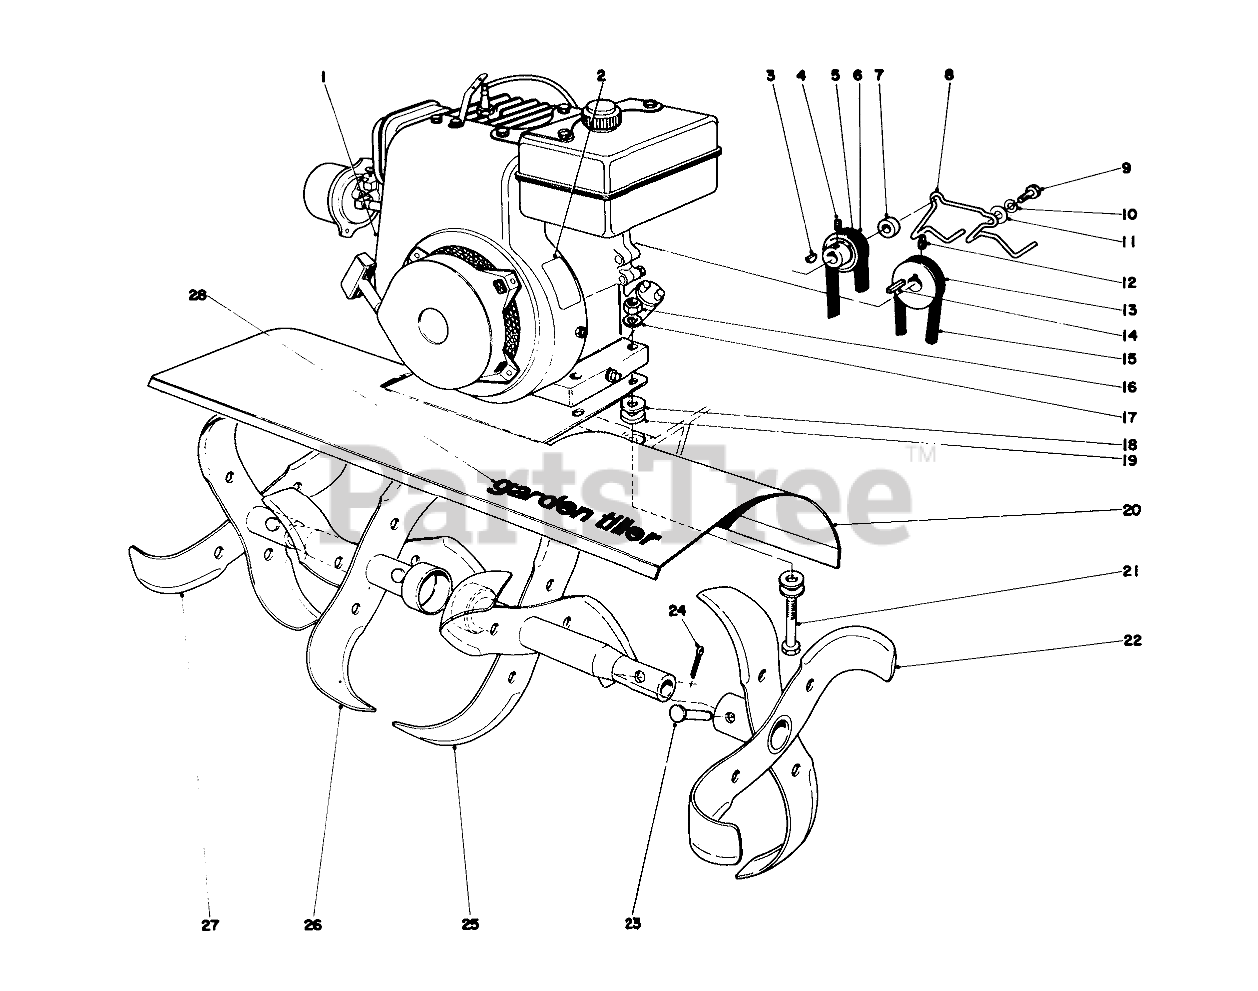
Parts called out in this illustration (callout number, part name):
1	Engine
2	Toro Lubrication
3	HI PRO KEY
4	Set Screw
5	Belt Reverse
6	PULLEY
7	Spacer
8	Belt Guide Upper
9	SCREW-HH
10	WASHER-LOCK
11	WASHER-FLAT
12	SCREW-SET, HSH
13	Engine Pulley
14	KEY-SQUARE
16	NUT-HEX
17	WASHER-LOCK
18	WASHER-FLAT
19	WASHER-FLAT
20	Shield
21	SCREW-HH
22	LH OUT SLASH TINE WA
23	TINE PIN
24	PIN-COTTER
25	Inner Tine L.H.
26	Inner Tine R.H.
27	RH OUT SLASH TINE EA
28	Decal
